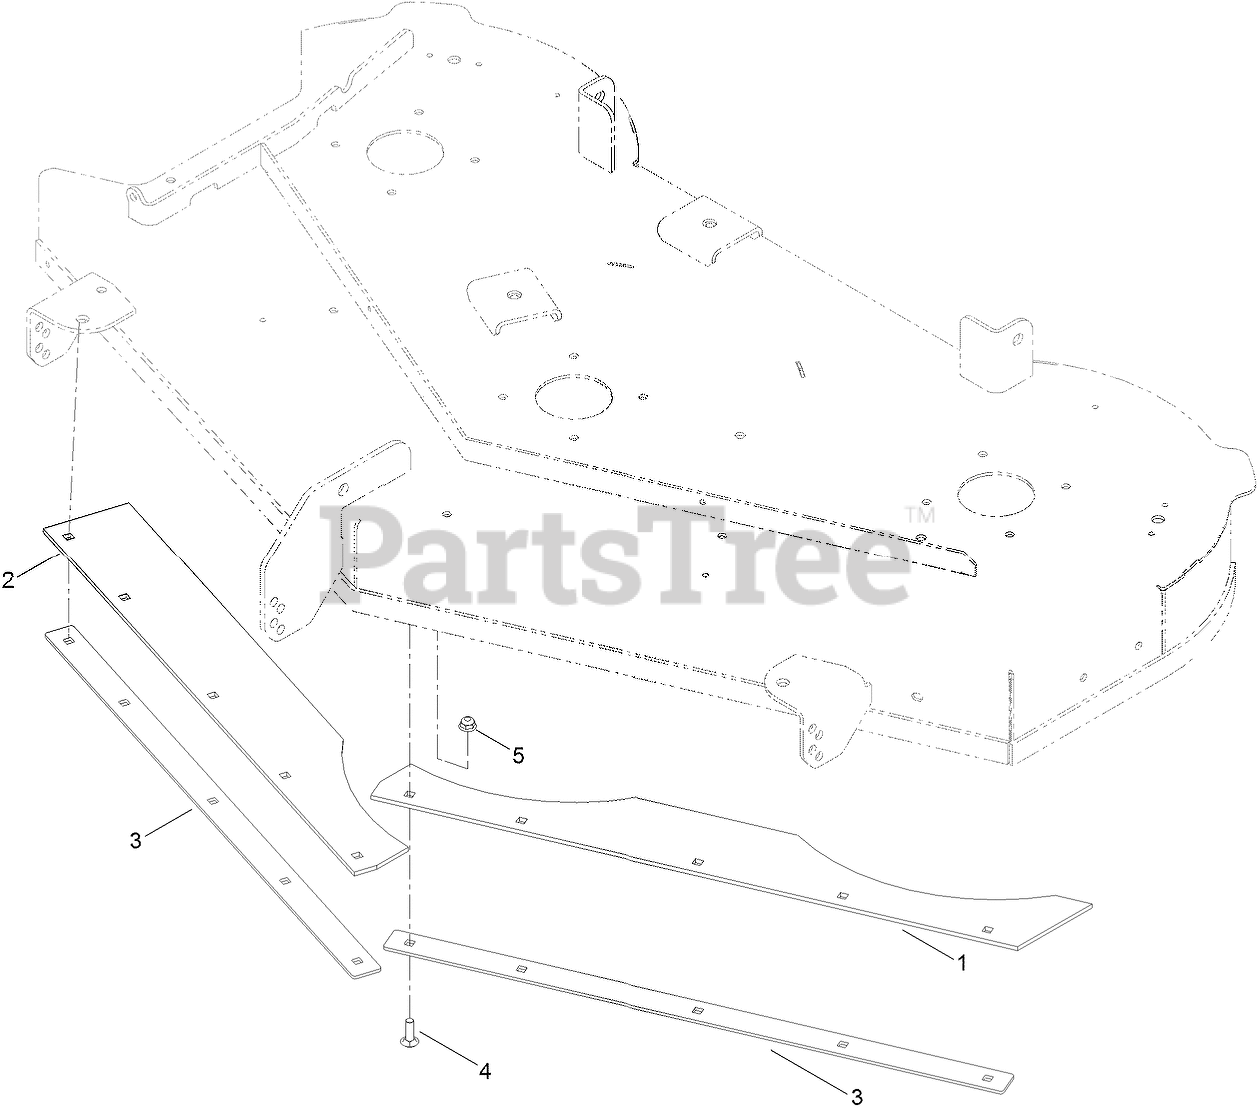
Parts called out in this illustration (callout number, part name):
1	SKIRT-RUBBER, FRONT
2	SKIRT-RUBBER, FRONT
3	PLATE-SKIRT
4	SCREW-CARR
5	NUT-HF
